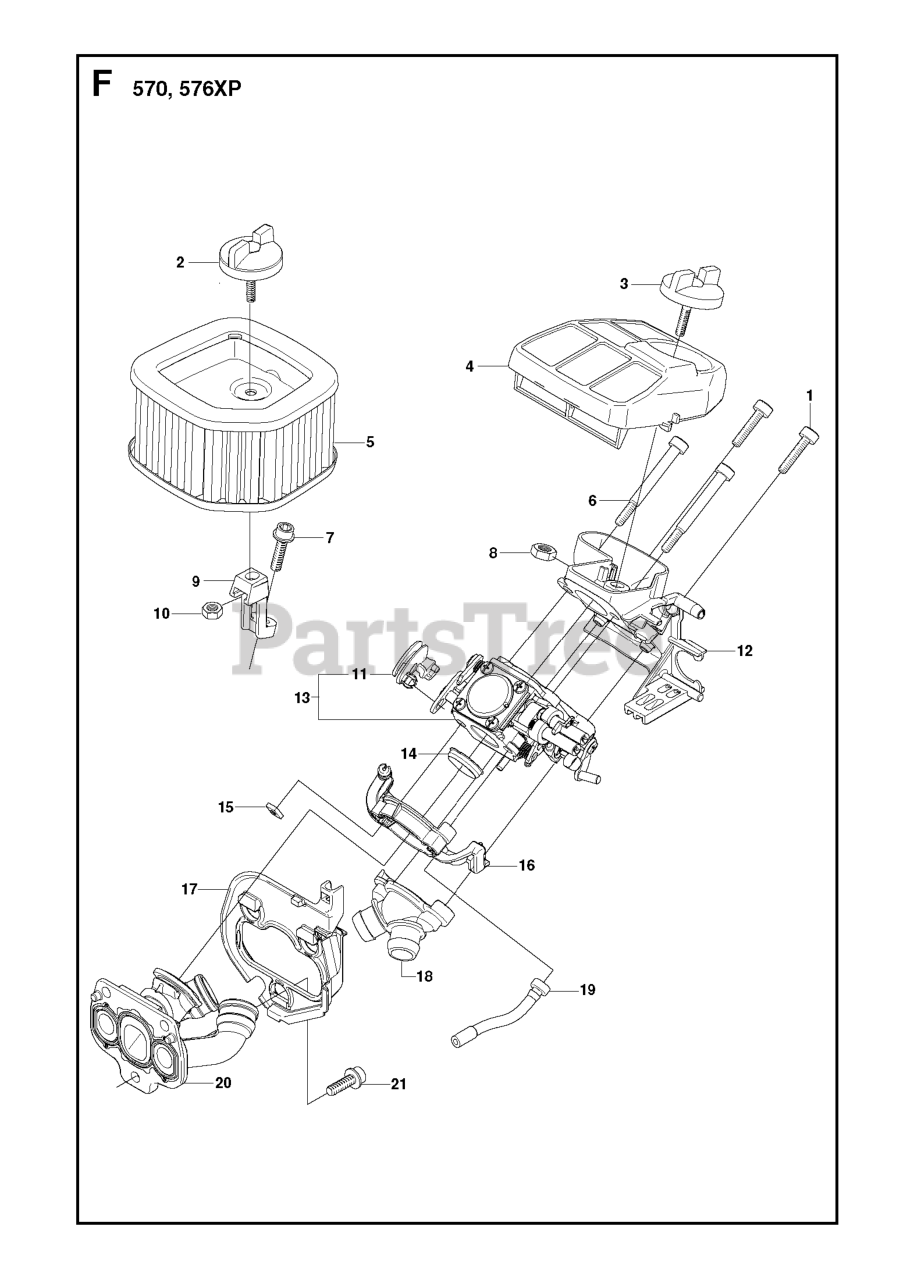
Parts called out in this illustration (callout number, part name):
4	RP AIR FILTER
4	%AIR FILTER
5	AIR FILTER WINTER
5	AIR FILTER
5	AIR FILTER HD 44
6	SCREW 4X46
12	FILTER HOLDER
13	RP CARBURETOR
